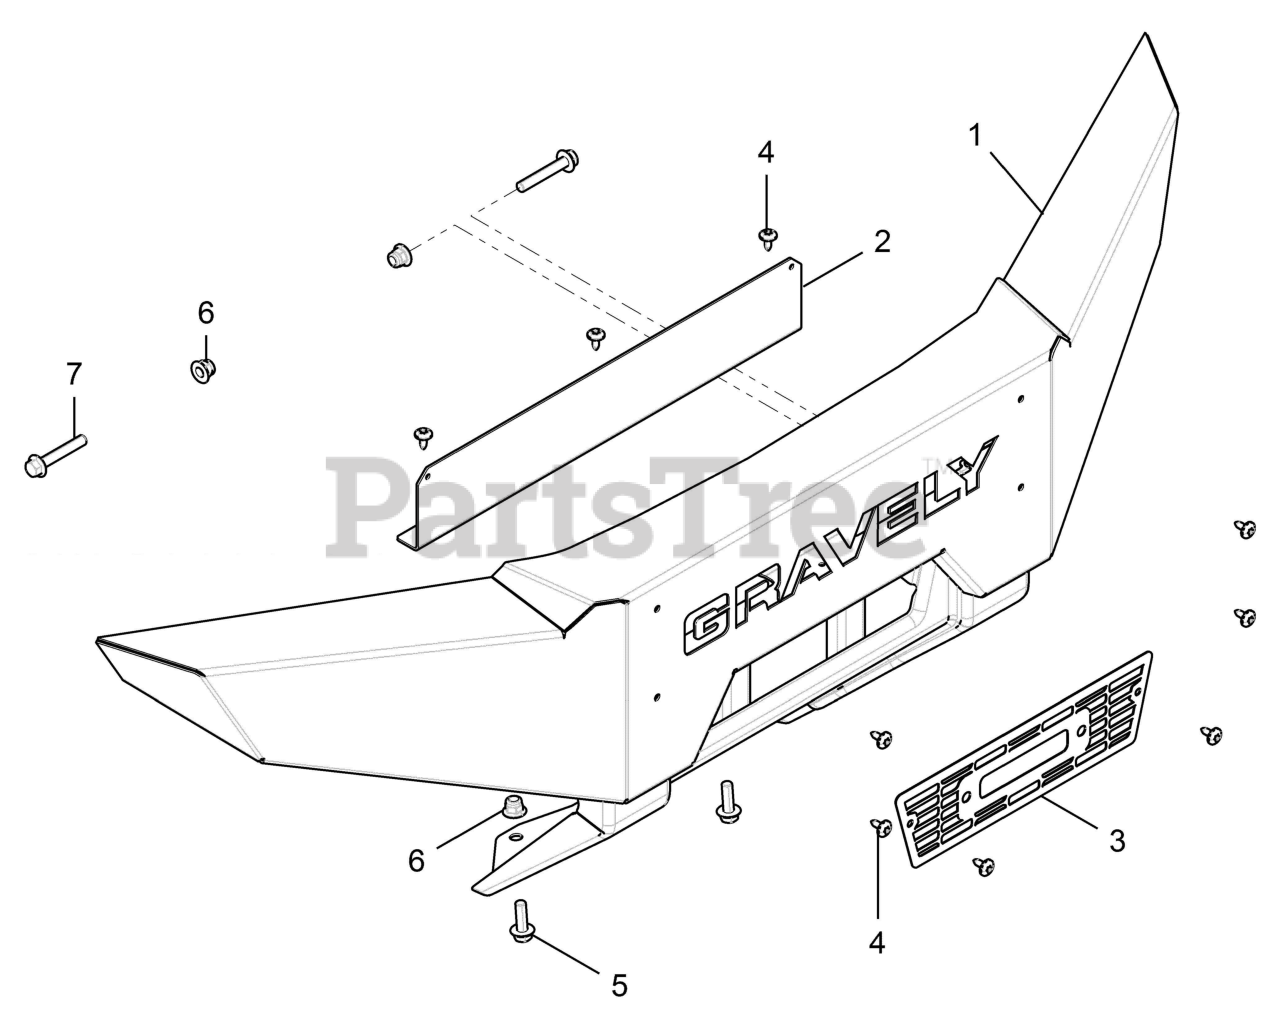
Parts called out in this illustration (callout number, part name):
1	WELD-BUMPER,FRONT,ARIENS,M BLK
2	PLATE, GRAVELY RED
3	SCREEN-BUMPER,BLK
4	SCR-M6X1X16 TR/TX-M
5	SCR-HXFL-M10X1.25X30 8.8 ZOD
6	NUT-M10X1.25,FLG,NYLOC-OLIVE D
7	BOLT-M10X1.25X60,HXFLG-OLIVE D
